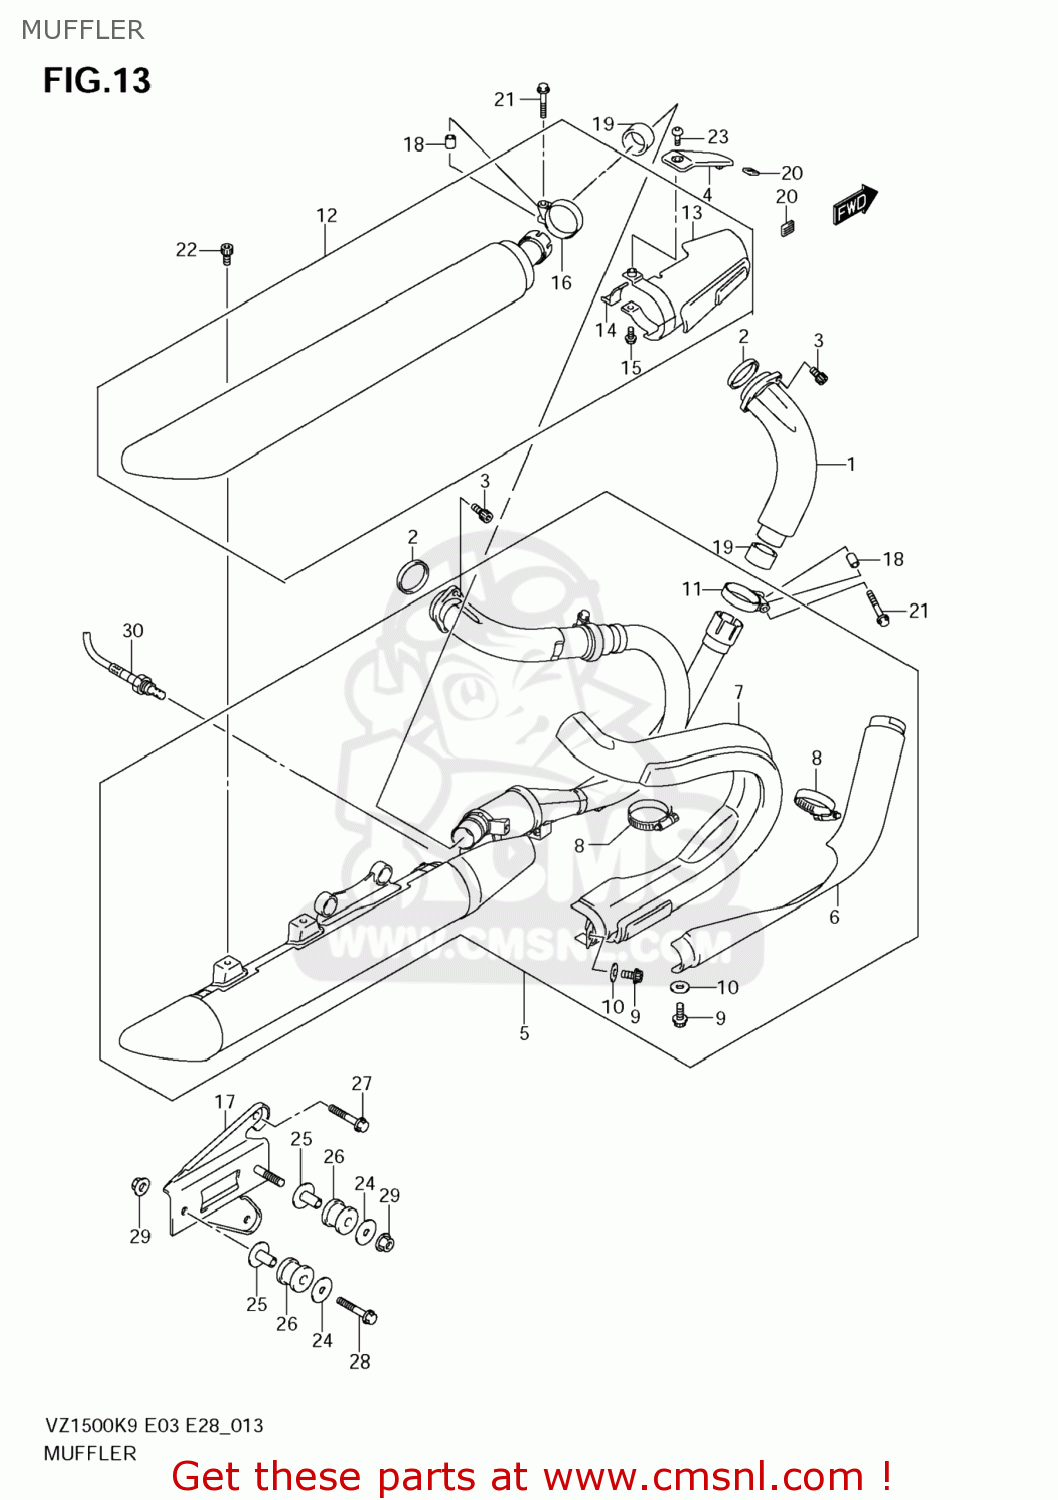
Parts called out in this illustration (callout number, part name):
1	PIPE,EXHAUST FR
2	GASKET,EXHAUST PIPE (NAS)
3	BOLT(8X25)
4	COVER,MUFFLER RR UP
5	MUFFLER,FR
6	COVER,EXHAUST FR
7	COVER,EXHAUST RR
8	CLAMP
9	BOLT
10	SPACER
11	CLAMP,MUFFLER CONNECTOR
12	BODY,MUFFLER RR
13	COVER,MUFFLER
14	CLAMP
15	BOLT
16	CLAMP,MUFFLER CONNECTOR
17	BRACKET,MUFFLER SUPPORT
18	SPACER,CLAMP
19	CONNECTOR
20	GROMMET
21	BOLT(8X35)
22	BOLT(8X20)
23	SCREW(6X10)
24	WASHER (8.5X33X1.6)
25	SPACER(8.6X12X27.1)
26	CUSHION
27	BOLT
28	BOLT
29	NUT
30	SENSOR,OXYGEN RR
